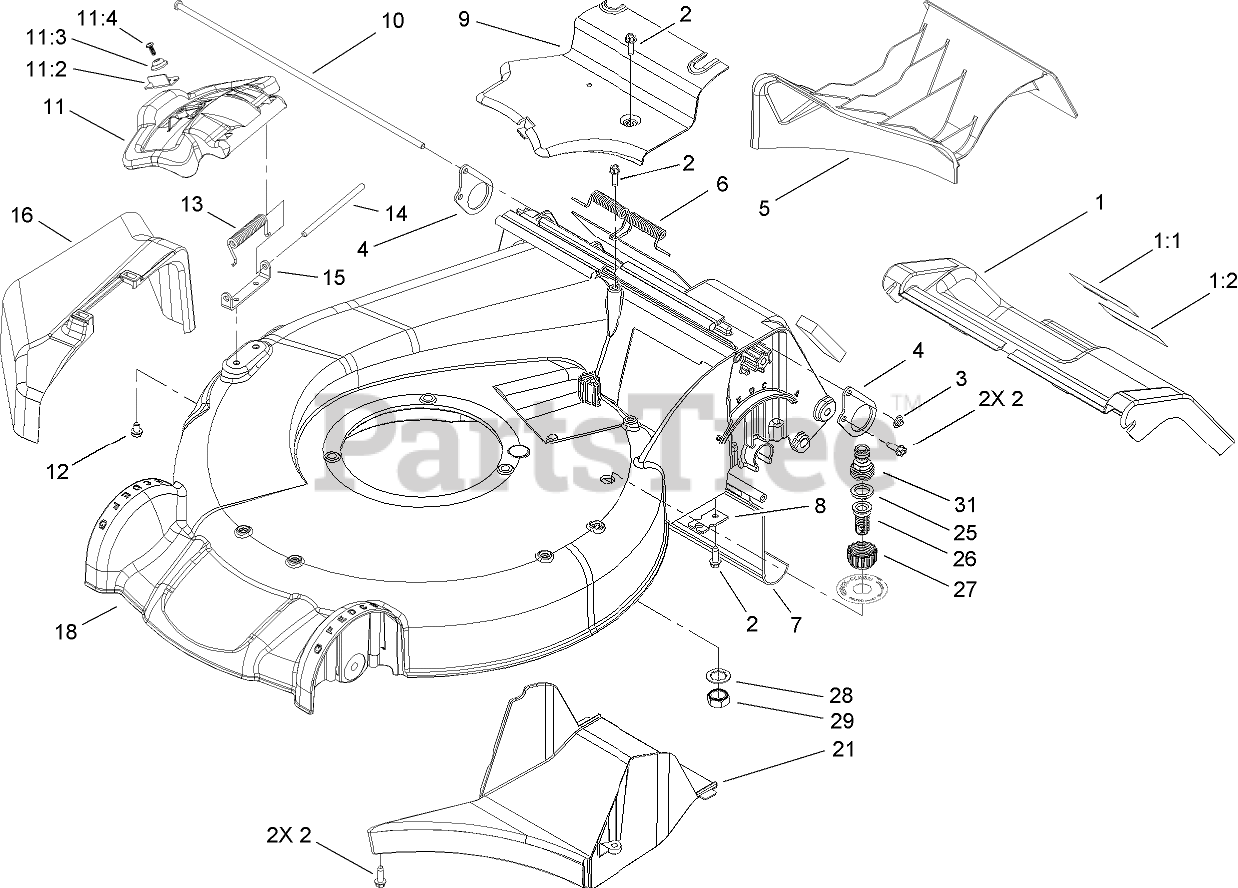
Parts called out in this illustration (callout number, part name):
1	DOOR-SERVICE
1:1	DECAL-WARNING
1:2	DECAL-WARNING
2	SCREW-HWHTF
3	NUT-SPEED
4	PLATE-SUPPORT, DOOR
5	MULCH PLUG ASM
6	Spring-Door, Rear
7	SHIELD-TRAILING
8	BRACKET-CABLE, TRACTION
9	COVER-BELT
10	ROD-SUPPORT, DOOR
11	DISCHARGE DOOR ASM
11:2	LATCH-DOOR
11:3	CAP-DOOR
11:4	SCREW-PLASTITE
12	SCREW-HWH
13	SPRING-TORSION
14	ROD-COVER
15	BRACKET-COVER
16	CHUTE-DISCHARGE, SIDE
18	HOUSING ASM
21	TUNNEL-DISCHARGE
25	WASHER-SEAL, WASHOUT PORT
26	PORT-WASHOUT
27	COUPLING-HOSE, WASHOUT PORT
28	WASHER-TOOTH, INTERNAL
29	NUT-JAM
31	ADAPTER-CONNECT, QUICK
